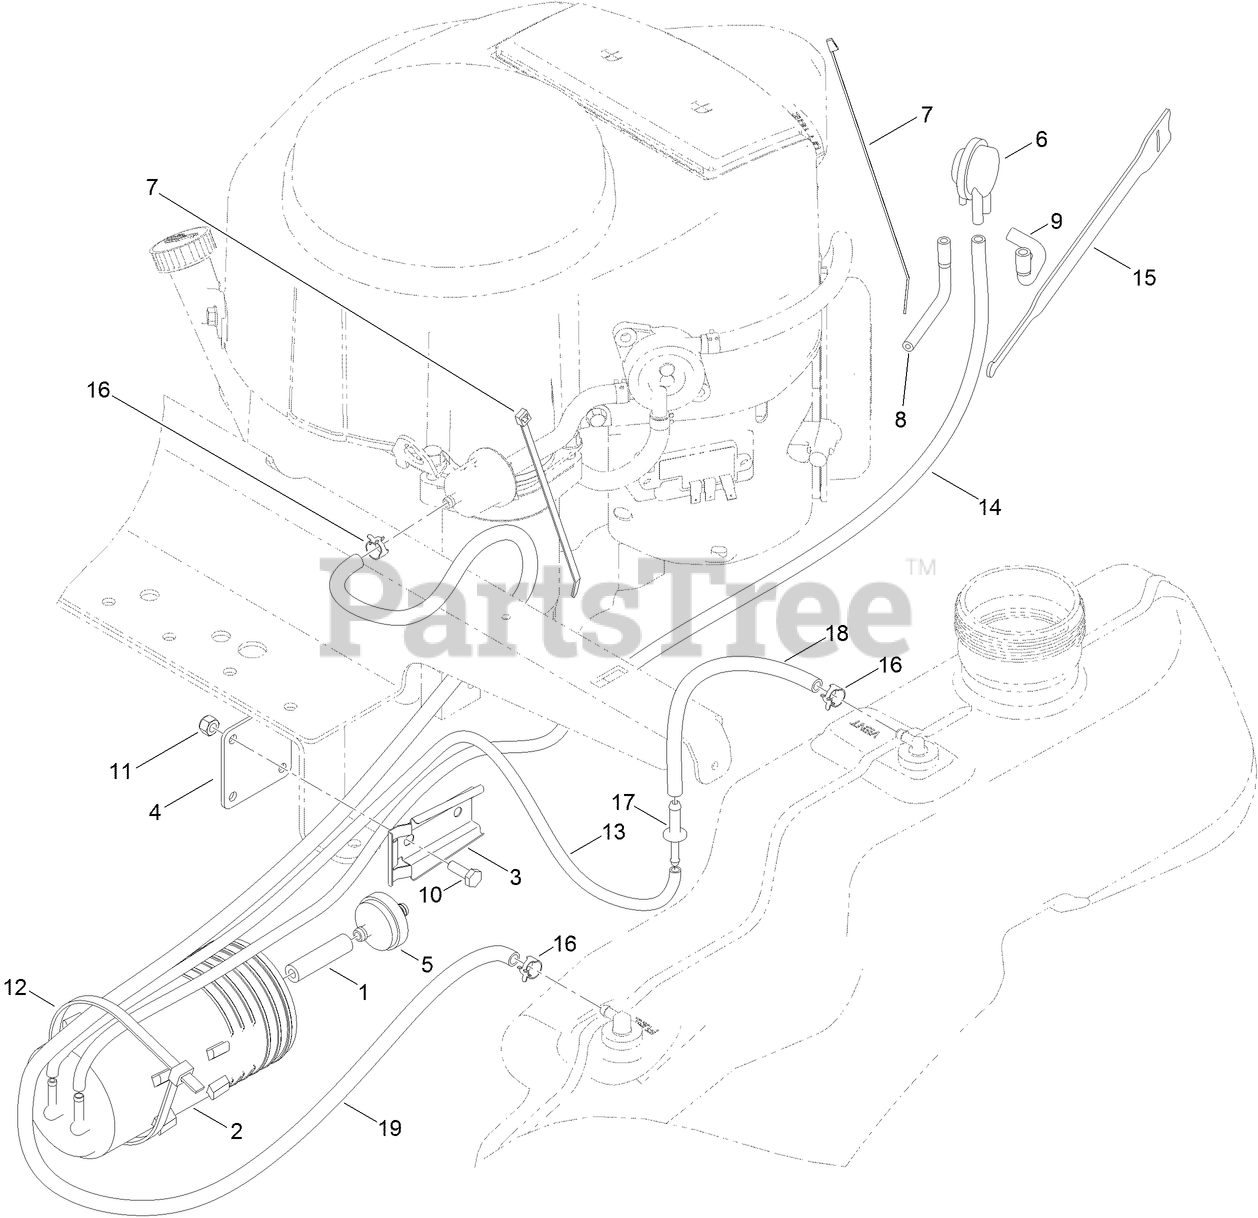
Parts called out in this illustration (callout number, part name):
1	HOSE-FUEL
2	CANISTER-CARBON, 800CC
3	BRACKET-CANISTER, CARBON
4	PLATE-ADAPTER
5	FILTER-FUEL, INLINE
6	VALVE-CONTROL, VACUUM
7	TIE-CABLE
8	HOSE-VENT, FORMED
9	HOSE-VENT, FORMED
10	SCREW-HH
11	NUT-LOCK, NI
12	TIE-CABLE
13	HOSE-FUEL
14	HOSE-FUEL
15	STRAP-VELCRO, CABLE TIE
16	CLAMP-HOSE
17	ADAPTOR-ORIFICE
18	HOSE-FUEL
19	HOSE-FUEL
